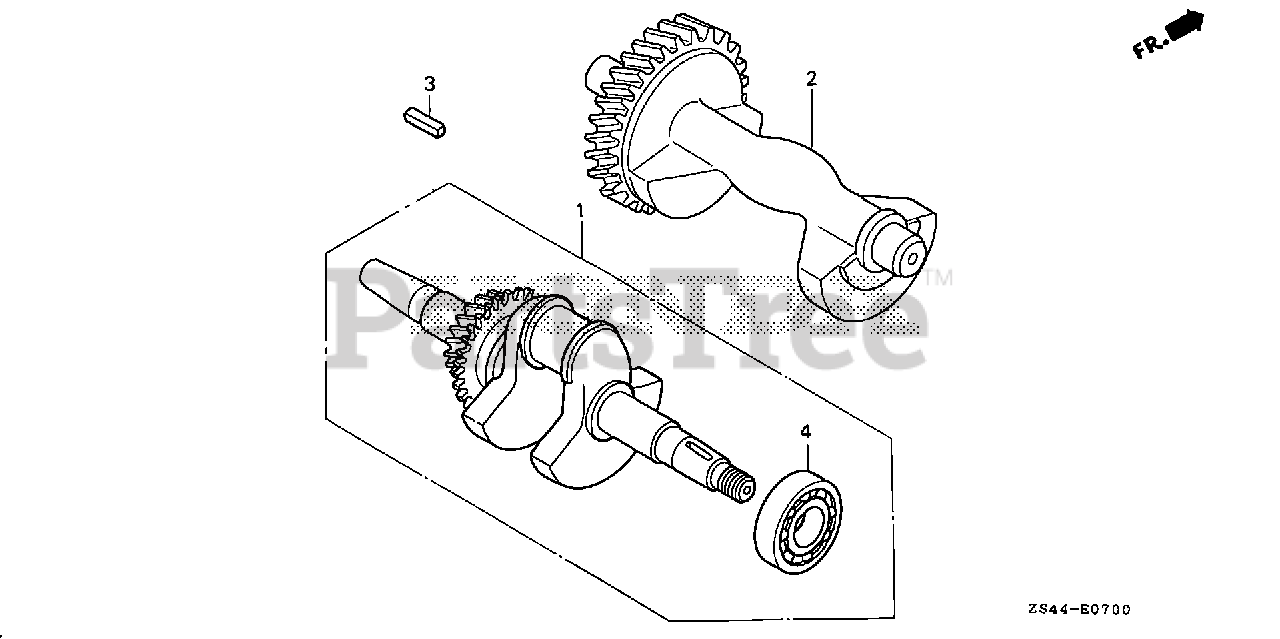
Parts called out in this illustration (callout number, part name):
1	CRANKSHAFT
3	KEY, SPECIAL WOODRUFF (25X18)
4	BEARING, RADIAL BALL (6206)
